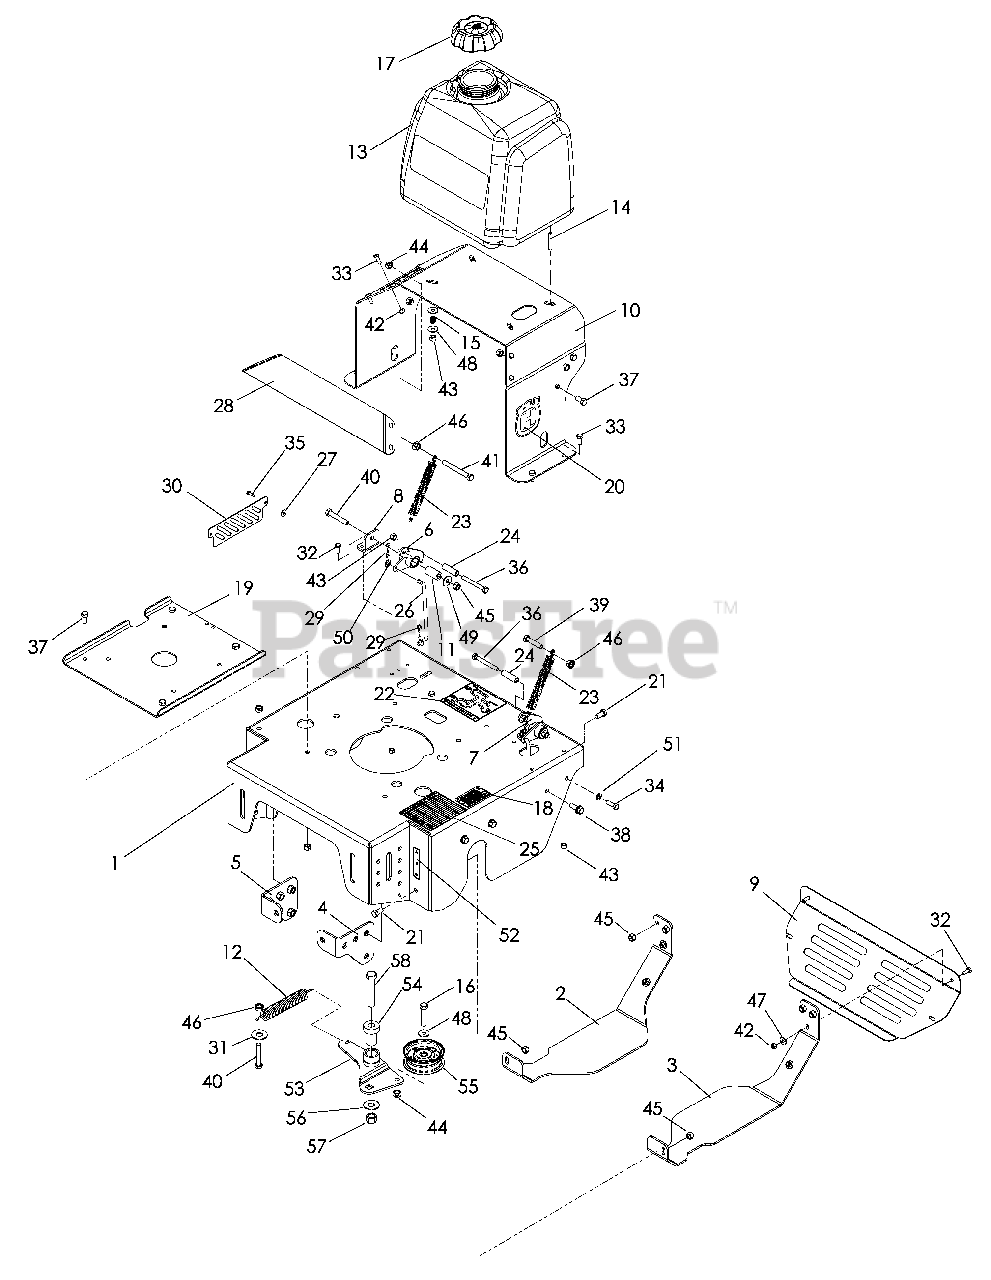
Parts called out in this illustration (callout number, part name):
1	REAR DECK W/DECALS
2	SKID PLATE, RIGHT
3	SKID PLATE, LEFT
4	NUT PLATE, LEFT
5	NUT PLATE, RIGHT
6	BELLCRANK, RIGHT, ETS
7	BELLCRANK, LEFT, ETS
8	CONTROL BRACKET
9	REAR GUARD
10	TANK SUPPORT
11	SLEEVE BUSHING
12	TRACTION SPRING
14	STUD, 5/16C
15	SPRING, TANK MOUNT
16	HCS, 3/8-16 x 1¾
17	FUEL CAP
18	DECAL, PROP 65
19	PLATE, ENGINE
20	DECAL, SMALL CROWN
21	HCS, 3/8-16 x 1
22	DECAL, BYPASS/BRAKE
25	DECAL, HEIGHT
26	CONTROL LINKAGE
27	WASHER, #10
29	HAIRPIN COTTER
31	WASHER, ½, SAE
32	HCS, ¼-20 x ¾
33	HCS, 5/16-18 x ¾
34	HCS, 5/16-18 x 1
35	SCRW, #10-24 x 5/8, WSH HD
36	HCS, 5/16-18 x 2¾
37	HCS, 3/8-16 x ¾
38	HCS, 3/8-16 x 1
39	HCS, 3/8-16 x 2½
40	HCS, 3/8-16 x 2¼
41	HCS, 3/8-16 x 3½, GR8
42	NUT, ¼C, NYLOC
43	NUT 5/16-18 HEX NYLOC
44	NUT, 3/8-16 HEX CNTRLK
45	NUT 3/8-16 HEX NYLOC
47	WASHER, ¼
48	WASHER, 5/16 STD FLT
49	WASHER, 3/8 FLAT STD
50	WASHER, 5/16, SAE
51	LOCK WASHER, 5/16
52	DECAL, POSITION
53	IDLER ARM, WELDMENT
54	IDLER SPINDLE
55	IDLER PULLEY
56	WASHER, ½
57	NUT ½ HEX NYLOC
58	HCS, ½-13 x 2¾
